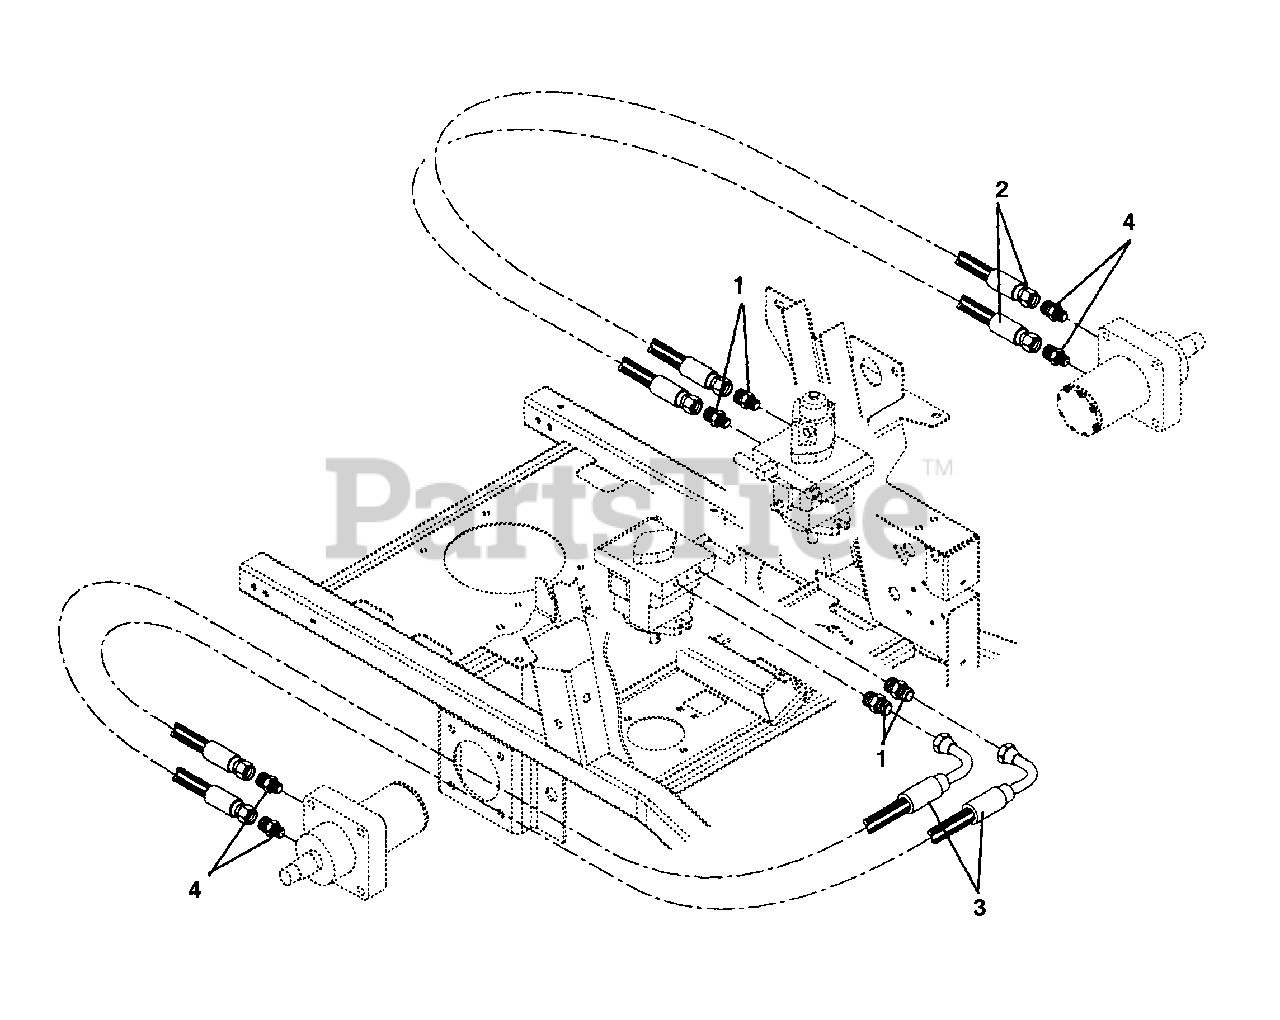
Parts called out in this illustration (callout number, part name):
1	ADAPTER, HYD ST 3/4 "O" TO 3/4
2	HOSE HYDRAULIC 1/2 19.75 LONG
3	HOSE,HYDRAULIC 29.50 LONG
4	ADAPTER, HYD ST 7/8 "O" TO 3/4
